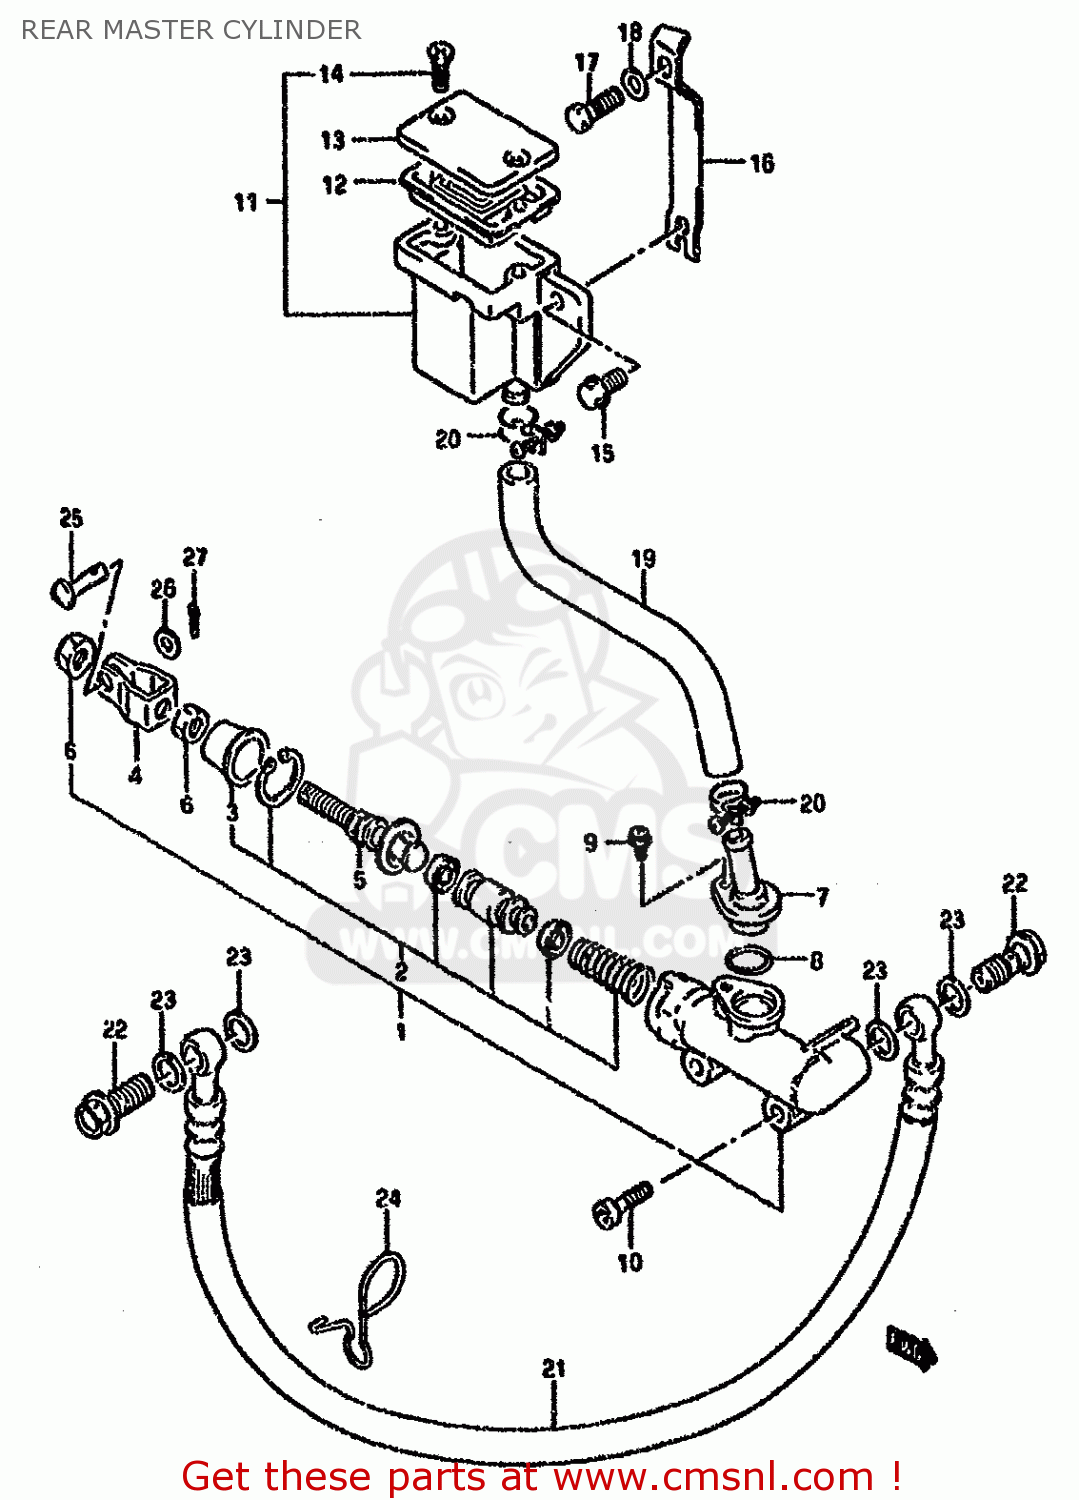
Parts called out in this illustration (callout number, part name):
1	CYLINDER ASSEMBLY,REAR MASTER
2	PISTON/CUP SET
3	BOOT
4	YOKE
5	ROD,PUSH
6	NUT
7	CONNECTOR
8	O RING
9	SCREW
10	BOLT
11	TANK ASSY,RESERVOIR
12	DIAPHRAGM
13	CAP
14	SCREW
15	BOLT
16	PLATE,RESERVOIR TANK
17	BOLT
18	WASHER,LOCK
19	HOSE,RESERVOIR TANK
20	CLIP
21	HOSE,RR BRAKE
22	BOLT UNION
23	WASHER(10X15X1.5)
24	GUIDE,BRAKE HOSE
25	PIN
26	WASHER
27	PIN
